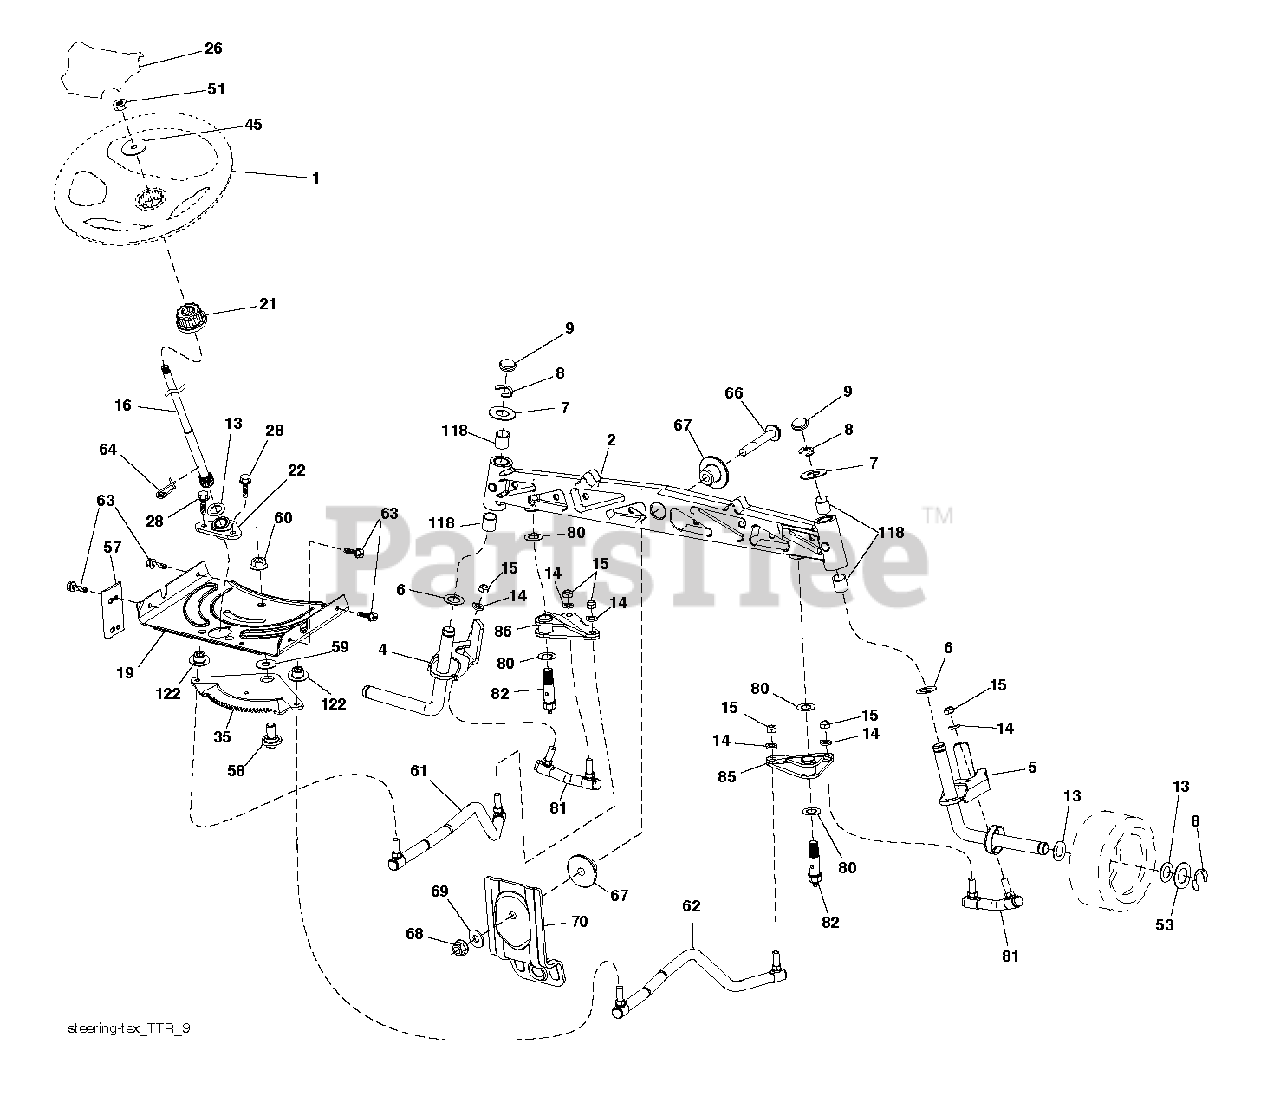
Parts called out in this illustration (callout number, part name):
1	WHEEL.STEER.HUSQ.SR.498.OVMLD
2	RP SUBASM.AXLE.CAST.NZTR.
4	SPINDLE WELDMENT.SPINDLE.LH.15
5	SPINDLE WELDMENT.SPINDLE.RH.15
6	THRUST WASHER
9	CAP.SPINDLE.BLACK
14	WASHER, LOCK 3/8
15	NUT CROWNLOCK 3/8-24
16	SHAFT SHAFT.STEERING.2HIGH.PLA
19	RP STEERING.WHEEL.ADAPTER
21	ADAPTER, WHEEL STNG..
22	BUSHING.ASM.STEERING.A
26	INSERT.CAP.WHL.STRG.HUSQ.PREM
28	SCREW, 3/8-16X3/4
35	GEAR GEAR.SECTOR.TEX.NZTR
45	WASHER 9/16"ID, 2 3/8"OD
51	NUT.HEX.1/2-20
53	WASHER.HARDENED
57	BRKT.UPSTOP.GT/LT.TEX
58	BOLT.SHOULDER.SECTOR.P
59	WASHER.THURST.SECTOR.S
60	NUT FLANGE LOCK 5/8-11
61	LINK SUBASM.LINK.DRAG.LH.NZTR
62	TUBE TUBE
63	SCREW
64	RETAINER.CLIP.SPRING.S
66	BOLT HEX FGHD 7/16-14 X 3 SERR
67	BUSHING.PM.FRONT AXLE
68	NUT.LOCK.FLANGE.7/16
69	WASHER.1.5X.505X.118
70	BRKT.DECK.SUSPENSION.F
80	THRUST WASHER
81	LINK SUBASM.LINK.CROSS.NZTR
85	PIVOT SUBASM.PIVOT.RH.NZTR
86	PIVOT SUBASM.PIVOT.LH.NZTR
118	BUSHING, AXLE CAST
122	CAP.GEAR.SECTOR.TEX
